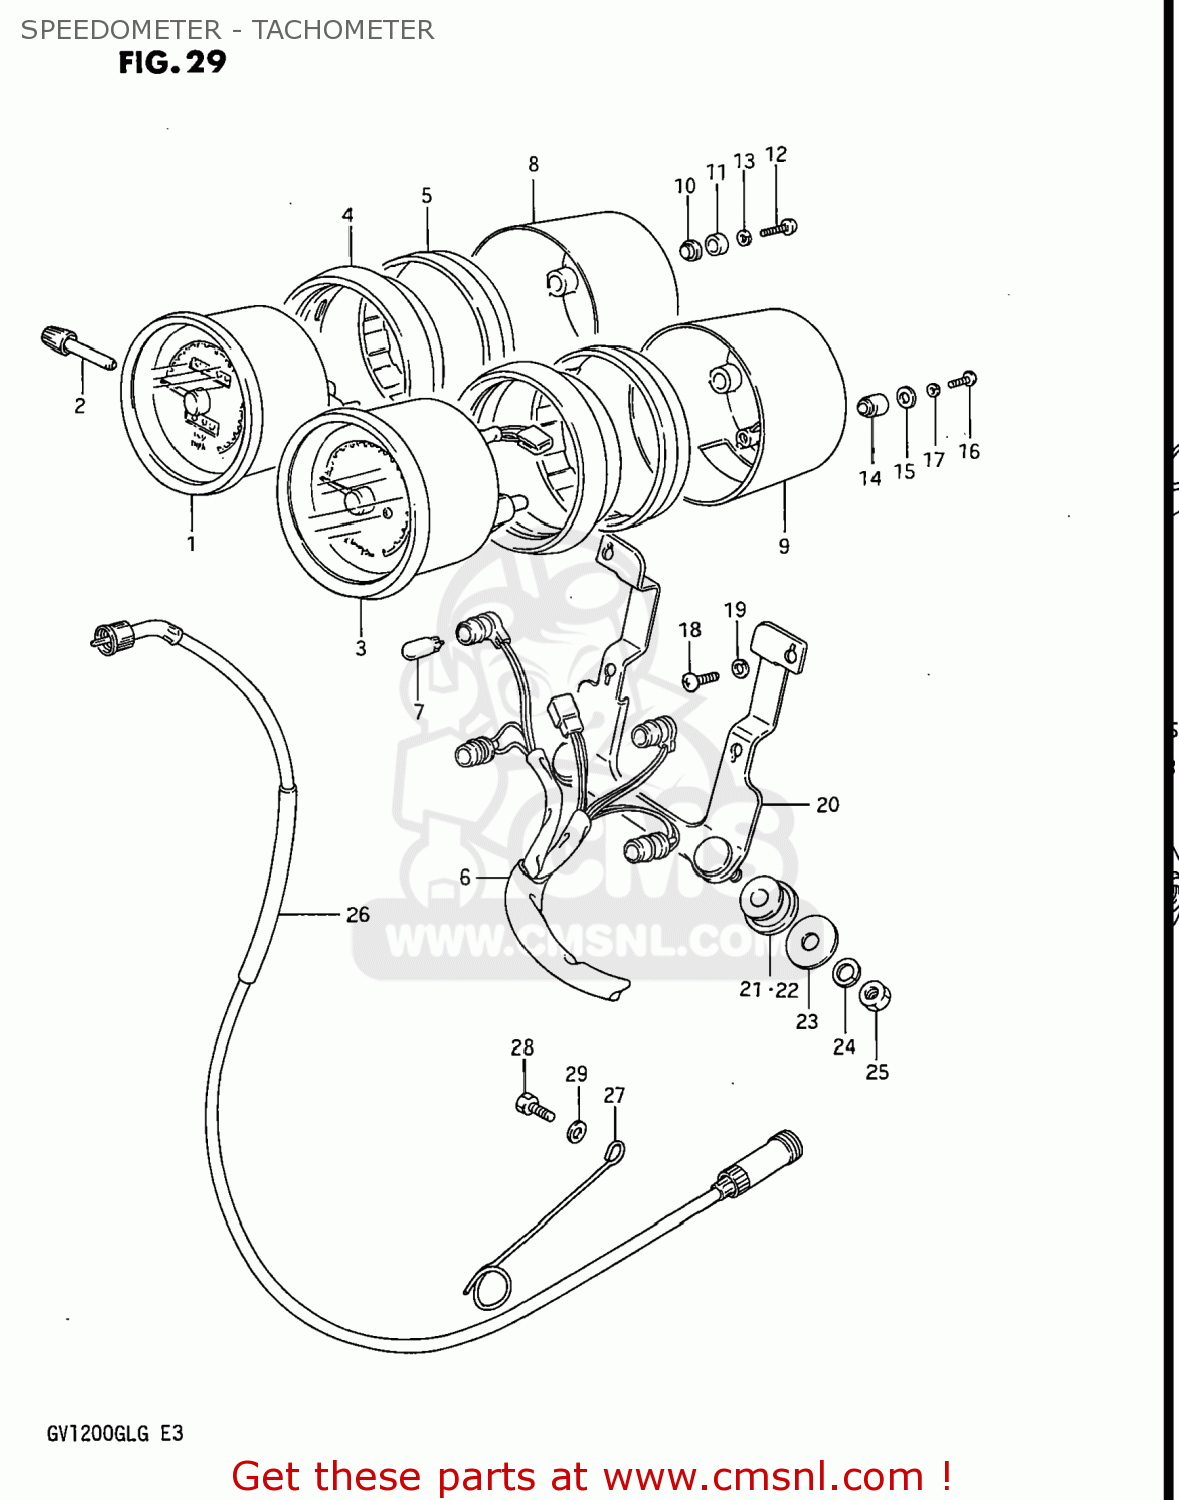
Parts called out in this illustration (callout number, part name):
1	METER,SPEEDOMETER (KM/MPH)
2	KNOB
3	TACHOMETER
4	COVER,METER
5	CUSHION,TACHOMETER
6	SOCKET,METER
7	BULB(12V3.4W,T10)
8	COVER,METER UNDER
9	COVER,TACHOMETER UNDER
10	CUSHION,METER
11	SPACER
12	SCREW
13	LOCK WASHER
14	CUSHION,TACHOMETER
15	WASHER
16	SCREW 4X10
17	LOCK WASHER
18	SCREW 5X10
19	LOCK WASHER
20	BRACKET,METER
21	CUSHION,METER
22	CUSHION,METER BRACKET
23	WASHER (8.5X20X1.6)
24	WASHER,LOCK,8.
25	NUT
26	CABLE ASSY,SPEEDOMETER
27	CLAMP,SPEEDOMETER CABLE
28	BOLT
29	WASHER
